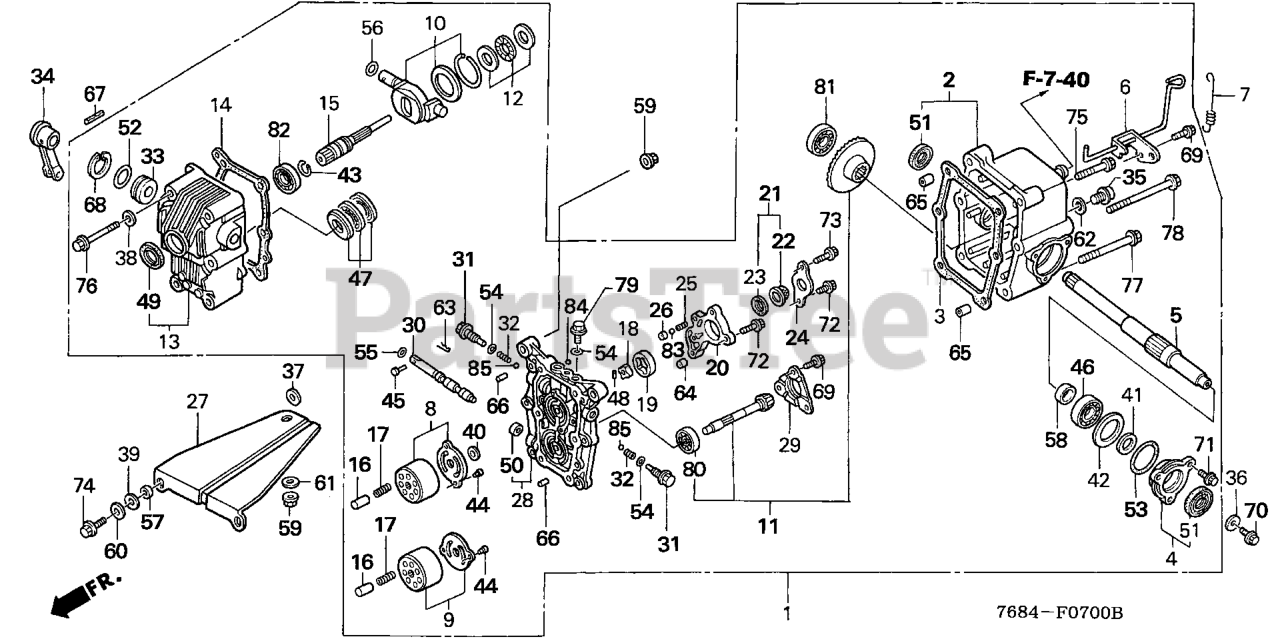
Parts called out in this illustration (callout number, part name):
1	TRANSMISSION ASSY.
2	CASE, RR. TRANSMISSION
3	GASKET, RR. TRANSMISSION CASE
4	HOLDER, OIL SEAL
5	SHAFT, CROSS
6	ARM, NEUTRAL VALVE
7	SPRING, NEUTRAL VALVE
8	PLATE SET, PUMP CYLINDER
9	PLATE SET, MOTOR CYLINDER
10	BOWL SET, CONTROL
11	GEAR SET, MOTOR SHAFT & BEVEL
12	BEARING SET, THRUST NEEDLE
13	CASE, PUMP
14	GASKET, PUMP CASE
15	SHAFT, PUMP
16	PISTON, PUMP (HOLE DEPTH=18MM)
17	SPRING, PISTON (5.8X34.5)
18	ROTOR, TROCHOID
19	VANE, TROCHOID
20	HOUSING, TROCHOID
21	FILTER ASSY., SUCTION
22	FILTER, SUCTION
23	SEAL, RUBBER
24	PLATE, FILTER CAP
25	SPRING, RELIEF VALVE
26	SEAT, RELIEF VALVE
27	PLATE, TRANSMISSION MOUNTING
28	PLATE, DISTRIBUTOR
29	HOLDER, BEARING
30	SPOOL, NEUTRAL VALVE
31	BOLT, CHECK VALVE
32	SPRING, CHECK VALVE
33	BUSH, CONTROL BOWL (B)
34	ARM, CLUTCH
35	BOLT, PLUG (14MM)
36	WASHER (6X17)
37	WASHER (8MM)
38	WASHER, SEALING (9X16X1.5)
39	WASHER, WAVE (12MM)
40	WASHER, THRUST (8MM)
41	WASHER, PLAIN (15MM)
42	SHIM A, BEVEL GEAR (1.5MM)
42	SHIM B, BEVEL GEAR (1.55MM)
42	SHIM C, BEVEL GEAR (1.6MM)
42	SHIM D, BEVEL GEAR (1.65MM)
42	SHIM E, BEVEL GEAR (1.7MM)
42	SHIM F, BEVEL GEAR (1.75MM)
43	CLIP, BEARING
44	PIN, DOWEL (3X5.8)
45	PIN, NEUTRAL VALVE
46	BEARING, RADIAL BALL (6904) (NTN CORP.)
47	BEARING, THRUST BALL (51204)
48	ROLLER (2.5X11.8)
49	OIL SEAL (17X30X5) (NIPPON)
50	DUST SEAL (9X15X5)
51	OIL SEAL (15X28X7)
52	O-RING (25X2.4)
53	O-RING (34.6X1.9)
54	O-RING (11X1.9)
55	O-RING (5.8X1.9)
56	O-RING (11.8X1.9)
57	COLLAR, TRANSMISSION MOUNT (8X12X4.7)
58	COLLAR, BEVEL GEAR
59	NUT, FLANGE (8MM)
60	WASHER, PLAIN (8MM)
61	WASHER, PLAIN (8MM)
62	WASHER, DRAIN PLUG (14MM)
63	PIN, LOCK (4MM)
64	PIN A, DOWEL (8X10)
65	PIN, DOWEL (10X12)
66	PIN, DOWEL (5X8)
67	PIN, SPRING (4X28)
68	CIRCLIP (INNER) (30MM)
69	BOLT, FLANGE (6X12) Use from Engine SN 2086984.
70	BOLT, FLANGE (6X16) Use from Engine SN 2056820.
71	BOLT, FLANGE (6X16)
72	BOLT, FLANGE (6X25)
73	BOLT, FLANGE (6X32)
74	BOLT, FLANGE (8X40) Use up to Engine SN 1003236.
75	BOLT, FLANGE (8X45)
76	BOLT, FLANGE (8X65)
77	BOLT, FLANGE (8X70)
78	BOLT, FLANGE (8X90)
79	BOLT, FLANGE (10X16)
80	BEARING, RADIAL BALL (6001)
81	BEARING, RADIAL BALL (6002)
82	BEARING, RADIAL BALL (6003)
83	BALL, STEEL (#6) (3/16)
84	BALL, STEEL (#7) (7/32)
85	BALL, STEEL (#8) (1/4)
